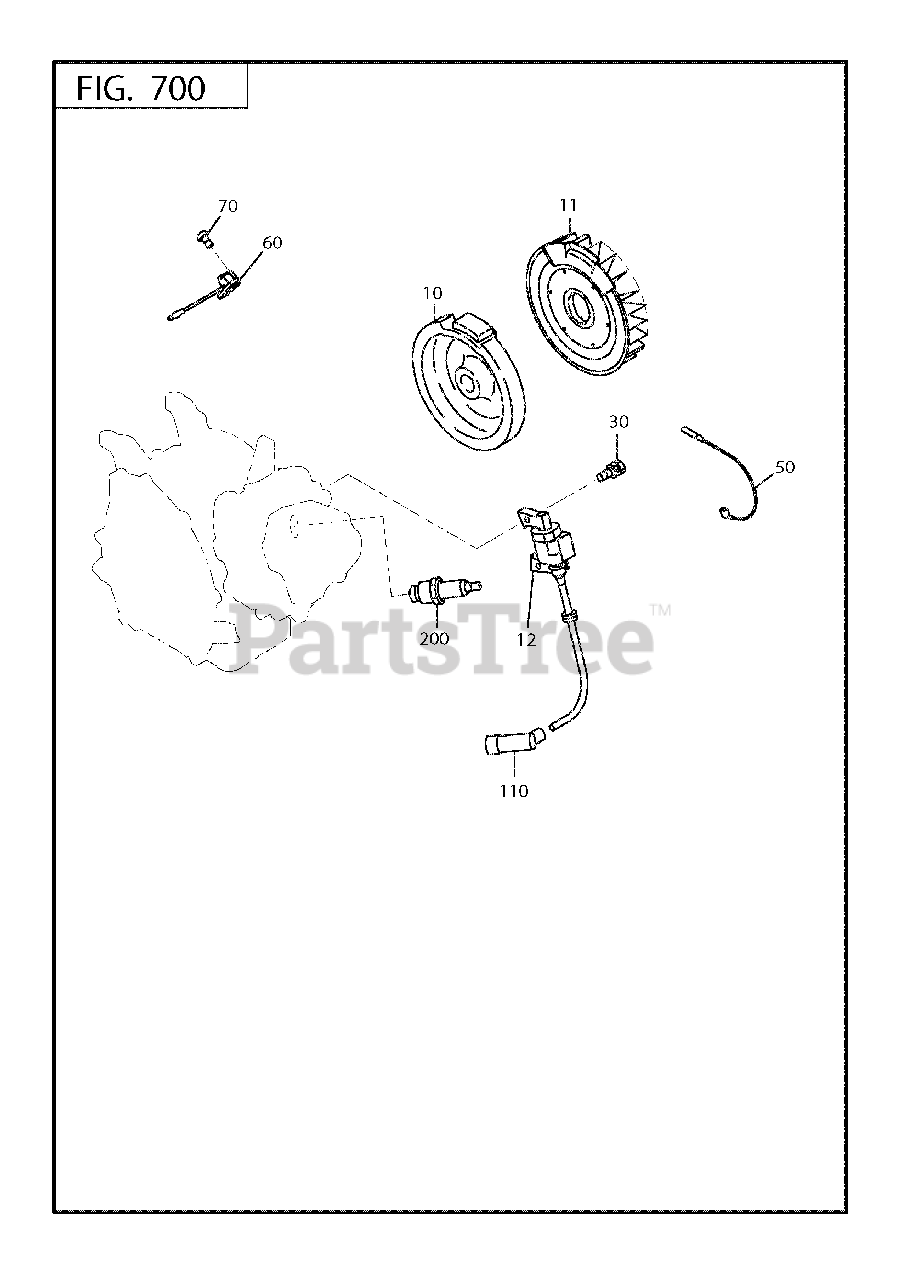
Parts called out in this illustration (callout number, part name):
11	COOLING BLOWER
12	IGNITION COIL CP
30	BOLT AND WASHER AY
110	SPARK PLUG CAP
